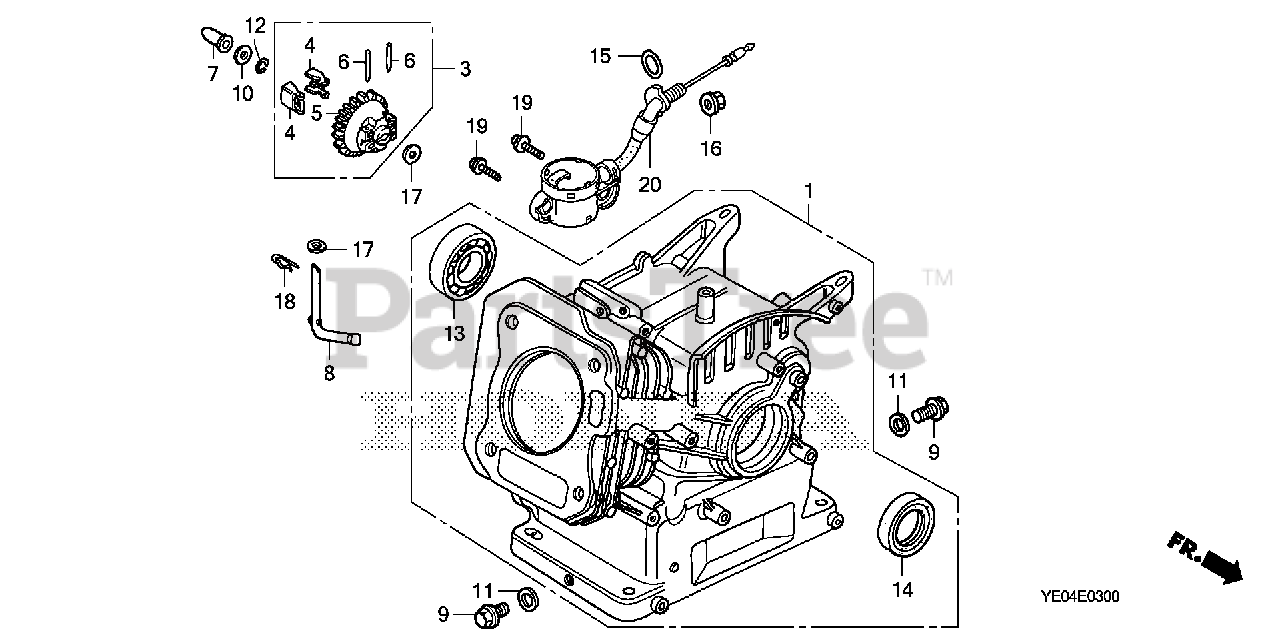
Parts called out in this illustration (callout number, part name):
1	CYLINDER ASSY. (OIL ALERT)
3	GOVERNOR ASSY.
4	WEIGHT, GOVERNOR
5	HOLDER, GOVERNOR WEIGHT
6	PIN, GOVERNOR WEIGHT
7	SLIDER, GOVERNOR
8	SHAFT, GOVERNOR ARM
9	BOLT, DRAIN PLUG
10	WASHER, THRUST (6MM)
11	WASHER, DRAIN PLUG (10.2MM)
12	CLIP, GOVERNOR HOLDER
13	BEARING, RADIAL BALL (6205TMB) (NTN)
13	BEARING, RADIAL BALL (6205) (NSK)
14	OIL SEAL (25X41X6) (NOK)
15	O-RING (13.5X1.5) (ARAI)
15	O-RING (14MM) (NOK)
16	NUT, FLANGE (10MM)
17	WASHER, PLAIN (6MM)
18	PIN, LOCK (8MM)
19	BOLT, FLANGE (6X12)
20	SWITCH ASSY., OIL LEVEL
